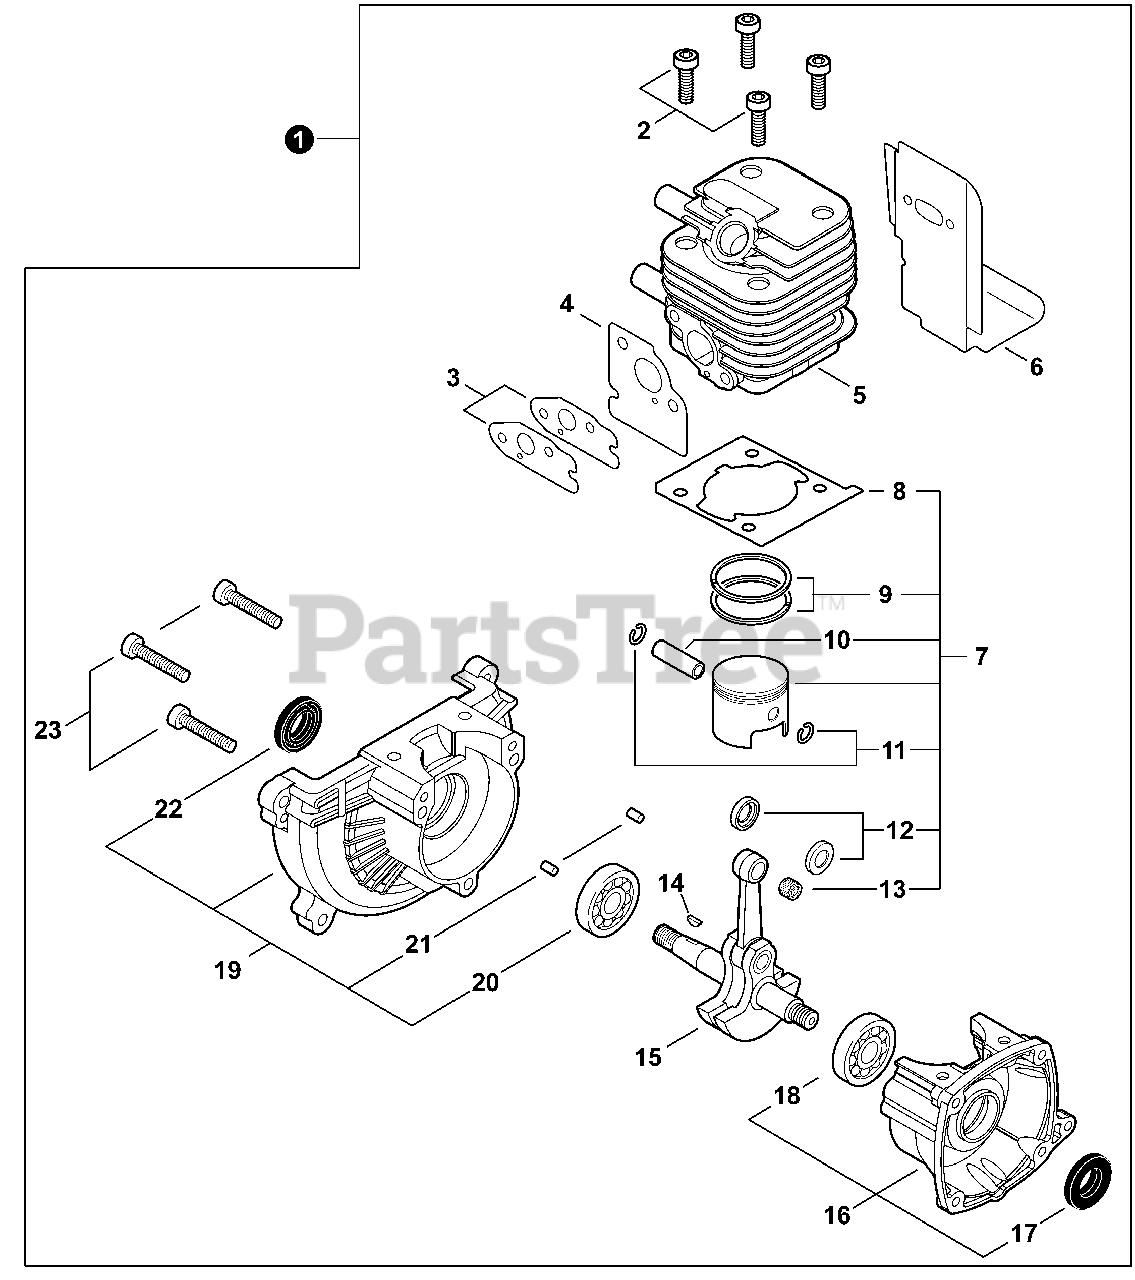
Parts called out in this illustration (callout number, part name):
1	SHORT BLOCK
2	BOLT 5×16
3	GASKET, INTAKE
4	HEAT SHIELD, INTAKE
5	CYLINDER
6	HEAT SHIELD, EXHAUST
7	PISTON KIT
8	GASKET, CYLINDER
9	RING, PISTON
10	PIN, PISTON
11	RING, SNAP
12	WASHER, THRUST 8
13	BEARING, NEEDLE 8
14	KEY, WOODRUFF 3×10
15	CRANKSHAFT ASSY
16	CRANKCASE ASSY, S
17	SEAL, OIL 12
18	BEARING, BALL 6001
19	CRANKCASE ASSY, M
20	BEARING, BALL 6001
21	PIN, LOCATING 4×8
22	SEAL, OIL 12
23	BOLT 5×25
